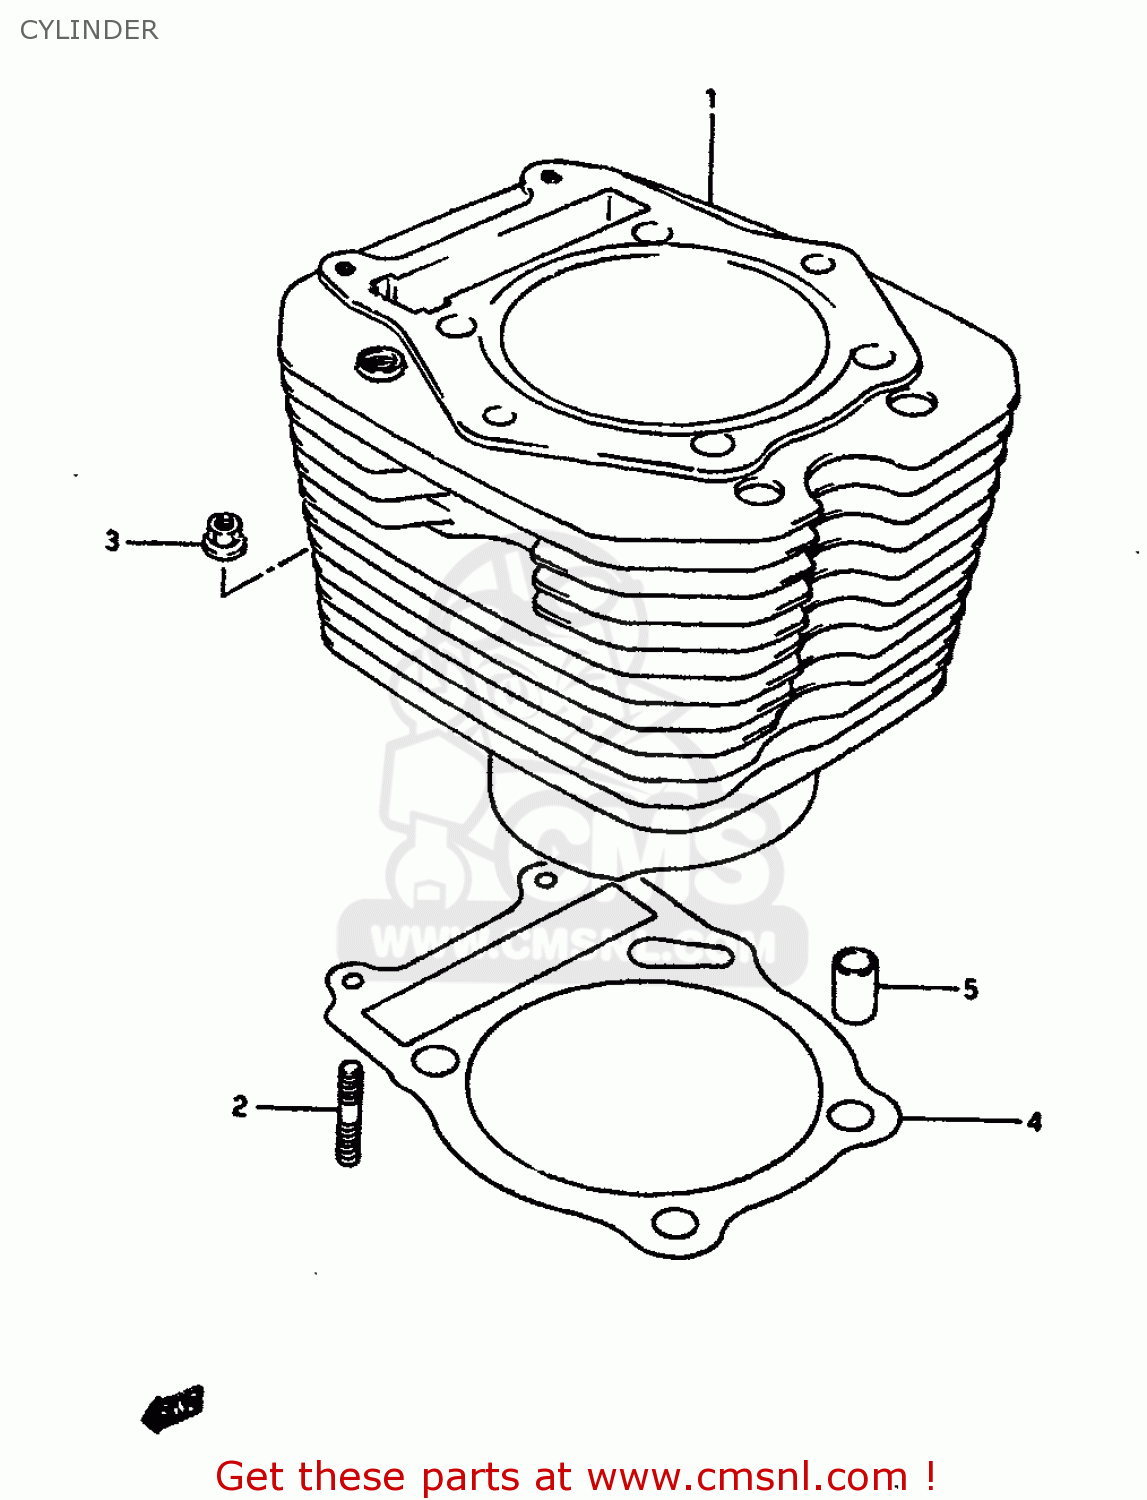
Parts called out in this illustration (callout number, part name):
1	CYLINDER
2	STUD BOLT L:20
3	NUT 6MM
4	GASKET,CYLINDER (NAS)
5	PIN
